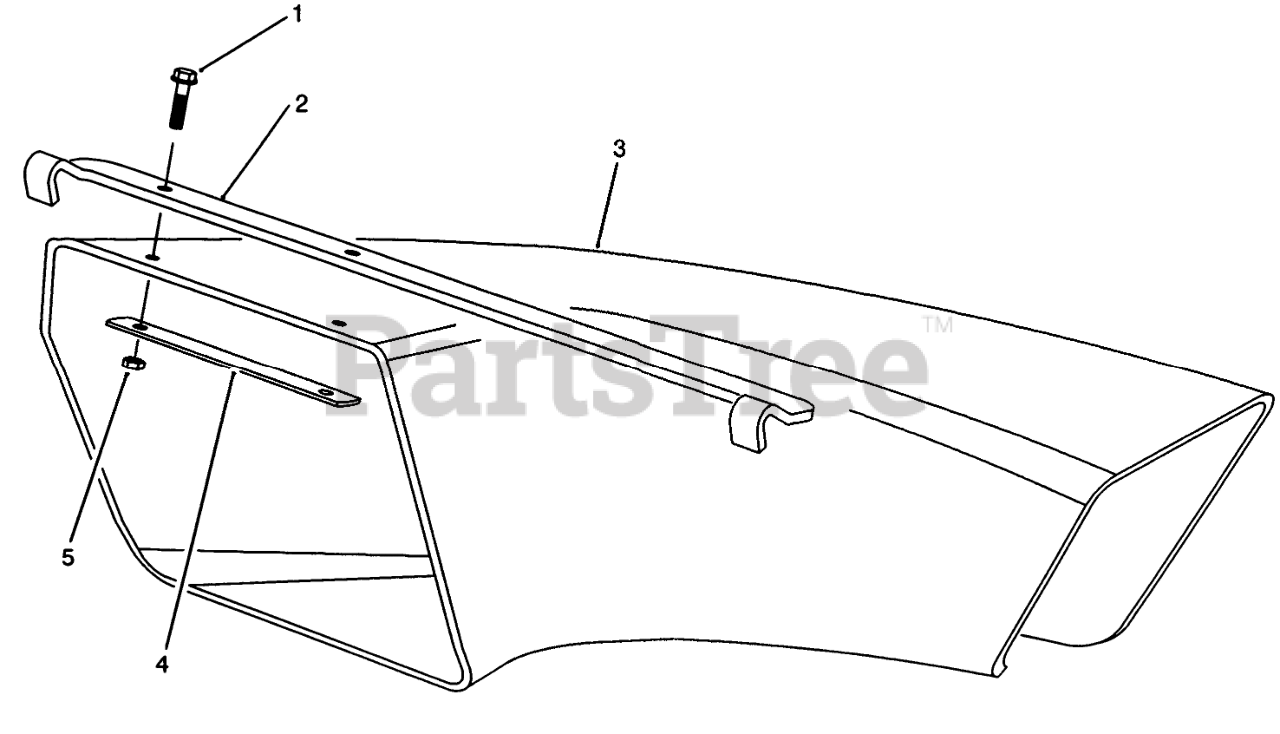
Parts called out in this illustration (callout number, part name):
1	SCREW-HWH
2	CHUTE HANGER BRACKET
3	Chute-Discharge
4	NUT-LOCK, NI
5	STRESS PLATE
